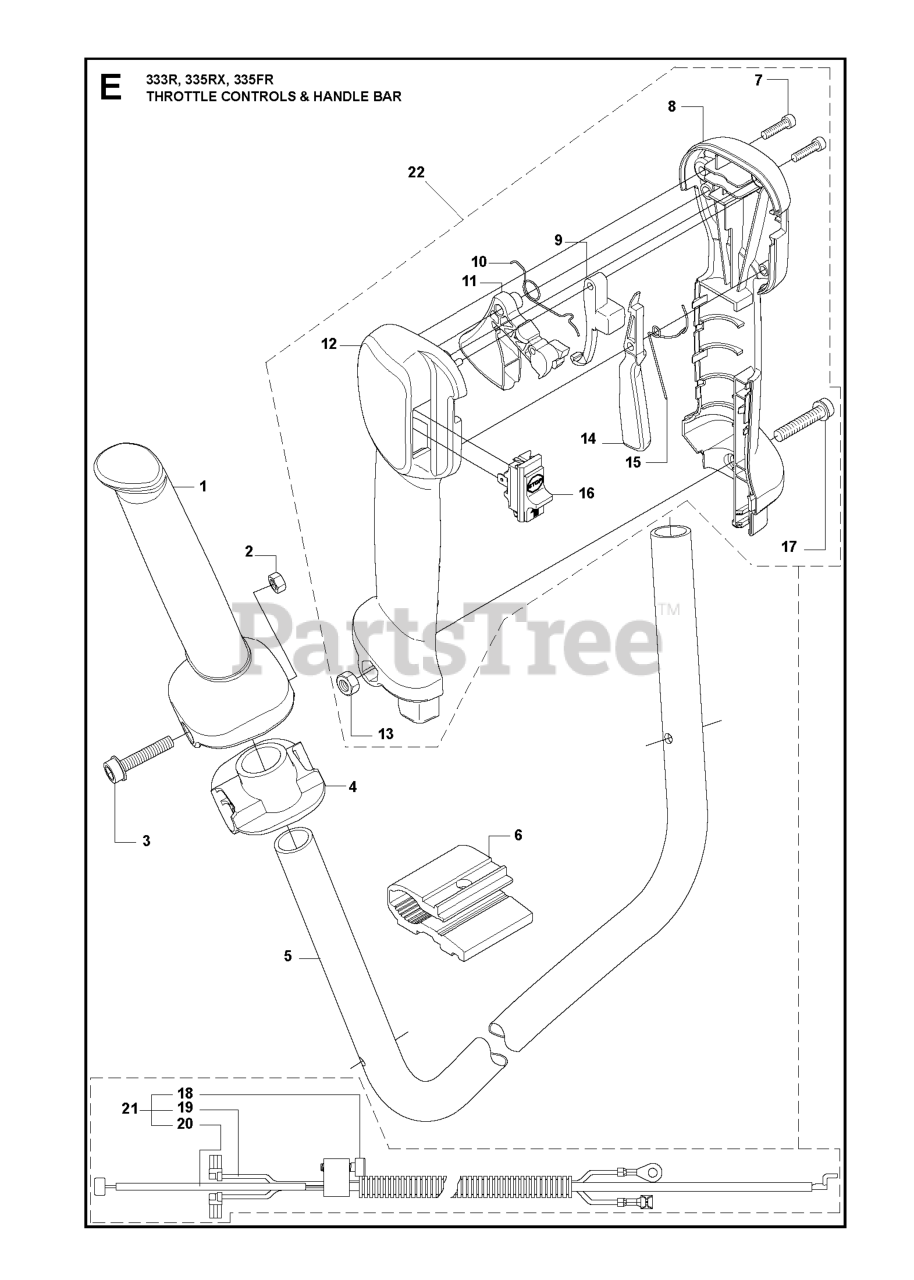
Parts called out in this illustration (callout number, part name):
6	CLAMP
7	SCREW
8	HANDLE
9	LOCKOUT STARTER THROTTLE
10	SPRING
11	THROTTLE CONTROL
12	HANDLE HALF LEFT
12	HANDLE
13	NUT
14	THROTTLE CONTROL
15	SPRING
16	STOP BUTTON
17	SCREW
18	SCREW
19	SHORT CIRCUIT CABLE
20	THROTTLE WIRE
21	WIRING KIT COMPLETE
22	HANDLE SYSTEM ASSY
